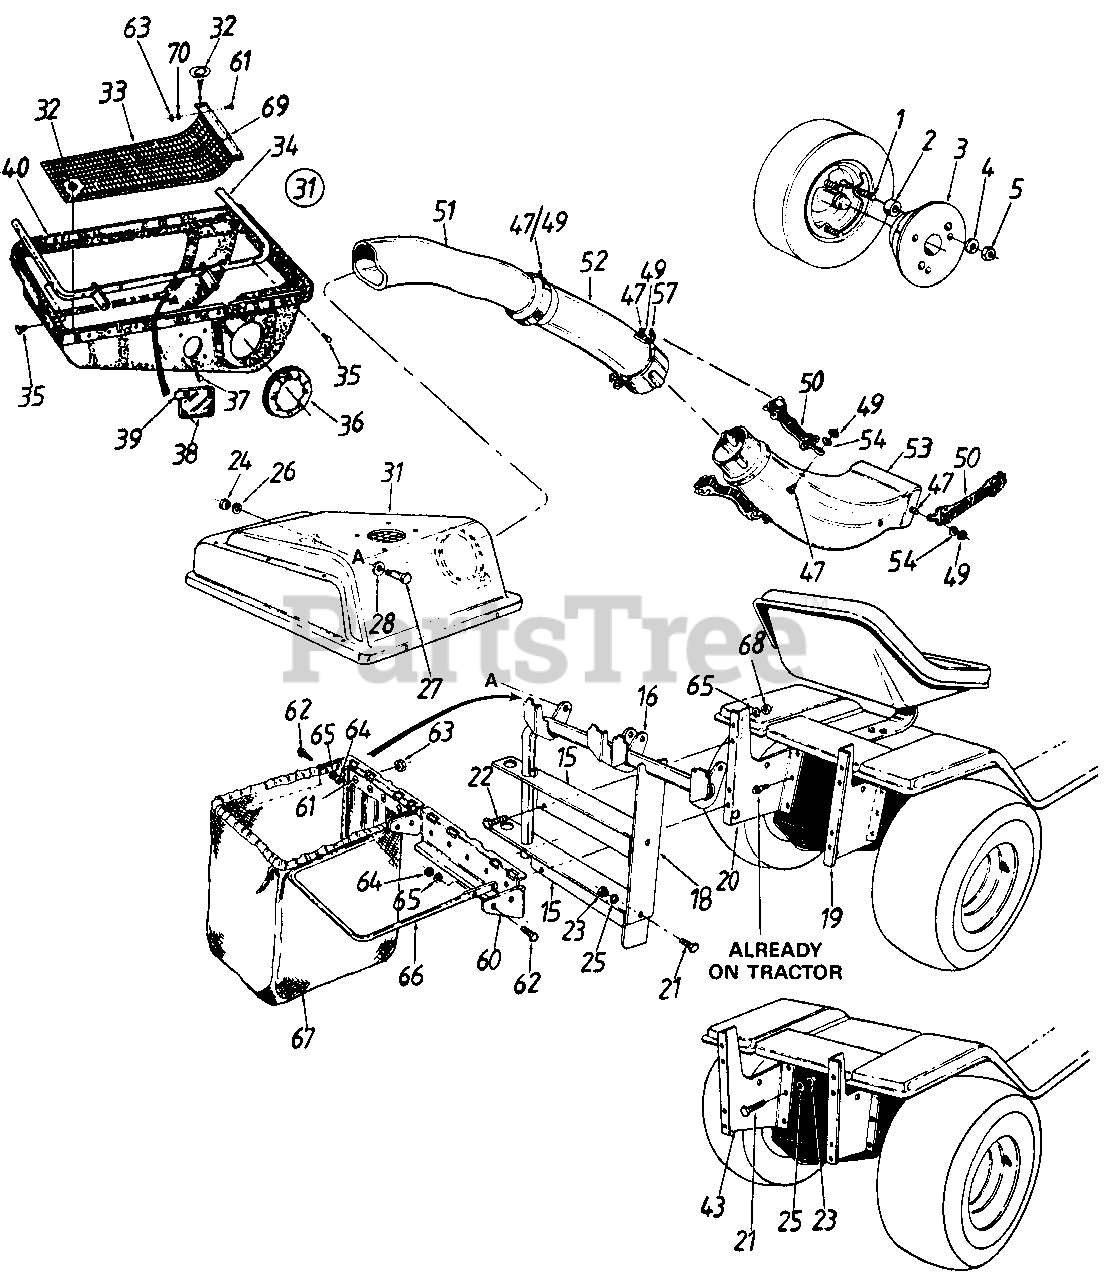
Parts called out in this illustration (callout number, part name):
1	Wheel Weight Snap Ring
2	Spacer
3	Wheel Weight
4	Lock Washer 5/16" I.D.
5	Hex Nut 5/16-18 Thread
15	Catcher Support Tube Mtg. Brkt.
16	Catcher Support Tube Assy.
18	Catcher Latch and Support Brkt.
19	Grass Catcher Support Brkt. - R.H.
20	Grass Catcher Support Brkt. - L.H.
21	Hex Bolt 5/16-18 x .75" Lg.*
22	Hex Bolt 1/4-20 x .62" Lg. - Grade 5
23	Hex Nut 5/16-18 Thd.*
24	Hex Nut 3/8-16 Thd.*
25	L.-Wash. 5/16" I.D.*
26	L.-Wash. 3/8" I.D.*
27	Shld. Bolt 3/8-16 x .500" Dia.
28	Bell.-Wash. .505" I.D. x 1.00" O.D.
31	Grass Catcher Cover Ass'y.
32	Twist Fastener
33	Screen
35	Hex Tap Scr. 1/4-20 x .5" Lg.
36	Seal
37	Truss Mach. 8-Tap Scr. #10 x .5" Lg.
38	Plastic Plate
39	Speed Nut
40	Grass Catcher Cover
47	Hex Bolt 1/4-20 x .50" Lg.*
49	Hex Ins. L.-Nut 1/4-20 Thd.
50	Retainer Strap Ass'y.
51	Catcher Elbow
52	Catcher Tube
53	Discharge Chute
54	L.-Wash. .27" I.D.
57	Retainer Hook Brkt.
61	Truss Mach. Scr. #10-24 x .50" Lg.
62	Hex Bolt 1/4-28 x .75" Lg.
63	Hex Sems Nut #10-24 Thd.
64	Hex Nut 1/4-28 Thd.*
65	L.-Wash. 1/4" I.D.*
67	Grass Catcher Bag
68	Hex Nut 1/4-20 Thd.*
69	Screen Mtg. Brkt.
70	Flat Wash. 1/4" I.D.
